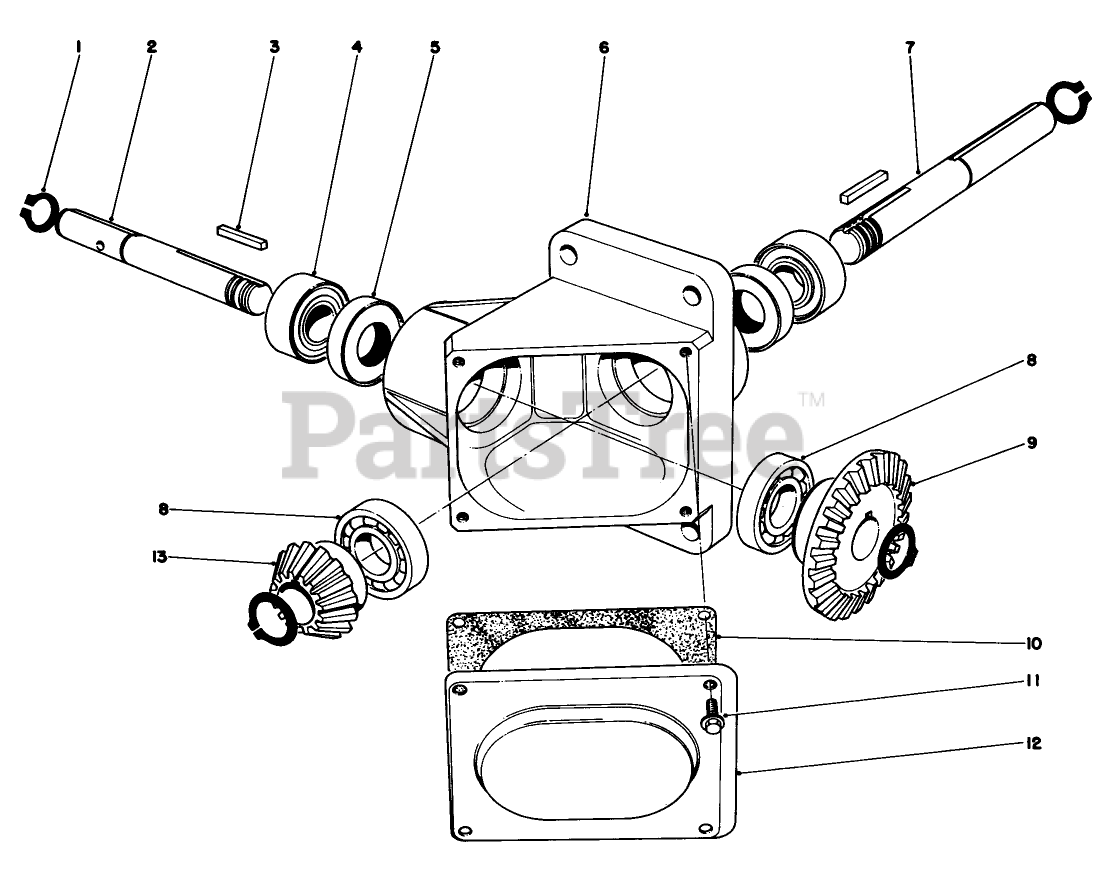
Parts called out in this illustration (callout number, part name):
1	Ring-Snap
2	GEAR BOX SHAFT (60120
3	Key
4	ROLLER BEAR (60124)
5	Oil Seal
6	GEAR BOX HSG
7	SHAFT-GEAR BOX
8	BEARING (R-12)
9	BEVEL GEAR (60128)
10	GASKET (60129)
11	SCREW
12	Cover Plate
13	BEVEL GEAR (60121)
